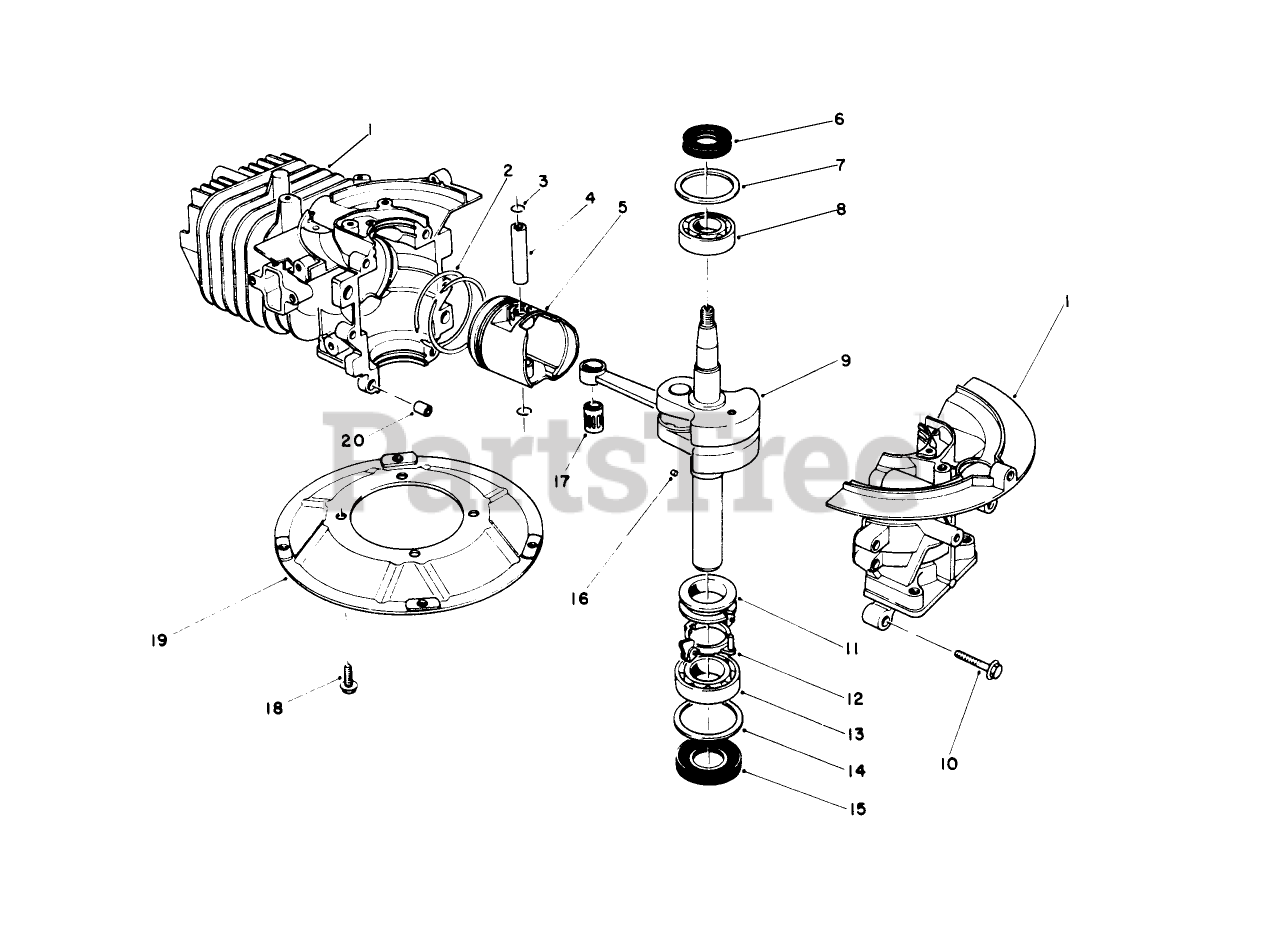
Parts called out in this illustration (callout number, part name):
2	RING SET
3	Circlip
4	Pin-Wrist
6	Oil Seal-Upper
7	WASHER-UPPER
8	Bearing-Upper (20 mm)
11	SPACER
12	BRACKET
13	LOWER BRG
14	WASHER-LOWER
15	SEAL-OIL
17	BEARING
19	PLATE-MOUNTING
